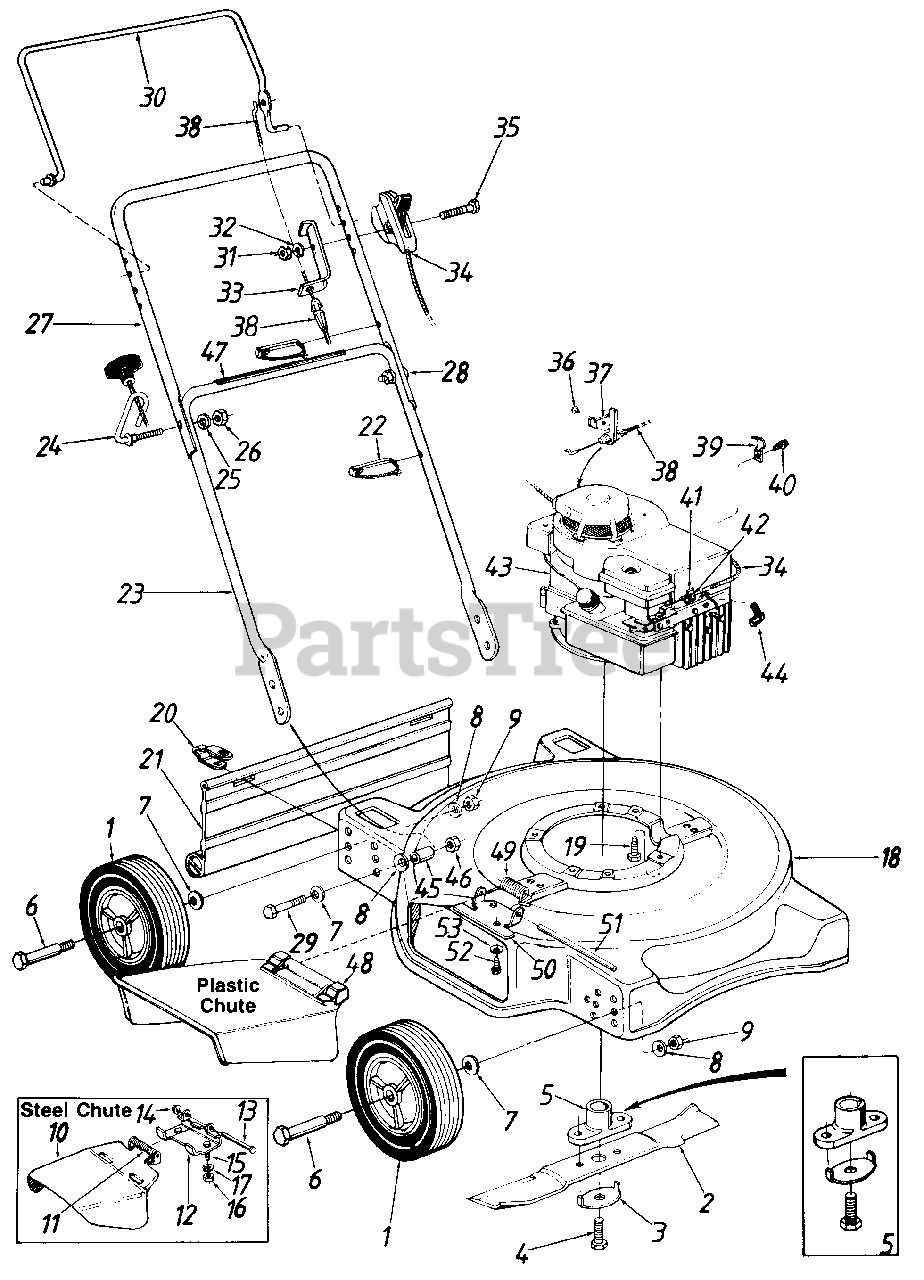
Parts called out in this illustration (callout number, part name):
1	Wheel Ass'y. Complete
2	20" Blade
3	Blade Bell-Washer
4	Hex Bolt 3/8-24 x 1.5" Lg.
5	Blade Adapter Kit (Keyed)
6	Shld. Bolt .498" Dia. x 1.64"
7	Bell-Wash. .380" I.D. x .88"
8	Bell-Wash. .39" I.D. x 1.13"
9	Hex Nut 3/8-16 Thd.*
10	Chute Deflector Ass'y
11	Torsion Spring
12	Adapter Plate
13	Pivot Pin
14	Speed Nut 1/4" Rod
15	Hex Bolt 1/4-20 x .5" Lg.*
16	Hex Nut 1/4-20 Thd.*
17	L-Wash. 1/4" I.D.*
18	20" Deck Ass'y.
19	Hex Wash. Hd. Scr. 3/8-16 x 1" Lg.
20	Hinge Clip
21	Rear Flap 16.75" Lg.
22	Cable Tie
23	Lower Handle (Painted)
24	Rope Guide Bolt
25	L-Wash. 5/16" I.D.*
26	Hex Nut 5/16-18 Thd.*
27	Upper Handle (Painted)
28	Curved Carriage Bolt 5/16-18 x 1.38" Lg.
29	Hex Bolt 3/8-24 x 1.5" Lg.
30	Control Handle
31	Hex Nut 1/4-28 Thd.
32	Spr. Wash. .265" I.D. x .562"
33	Cable Mounting Bracket
34	Throttle Control Ass'y. Comp.
35	Hex Bolt 1/4-28 x 1.75" Lg.
36	Pop Rivet
37	Cable Bracket
38	Control Cable-36"
39	Casing Clamp
40	Hex B-Tap Scr. #10 x .38" Lg.
41	Casing Clamp
42	Hex Wash. Hd. AB-Tap Scr. #8 x .50" Lg.
43	Engine
44	Spark Plug Boot
45	Spacer .381" I.D. x .56" O.D. x.75" Lg.
46	Hex L-Nut 3/8-24 Thd.
47	Instruction Label-Handle
48	Chute Deflector Ass'y.
49	Torsion Spring
50	Adapter Plate
51	Hinge Pin
52	Hex Self-Tap Scr. 1/4-20 x .5" Lg.
53	Bell-Wash. 114" I.D.
